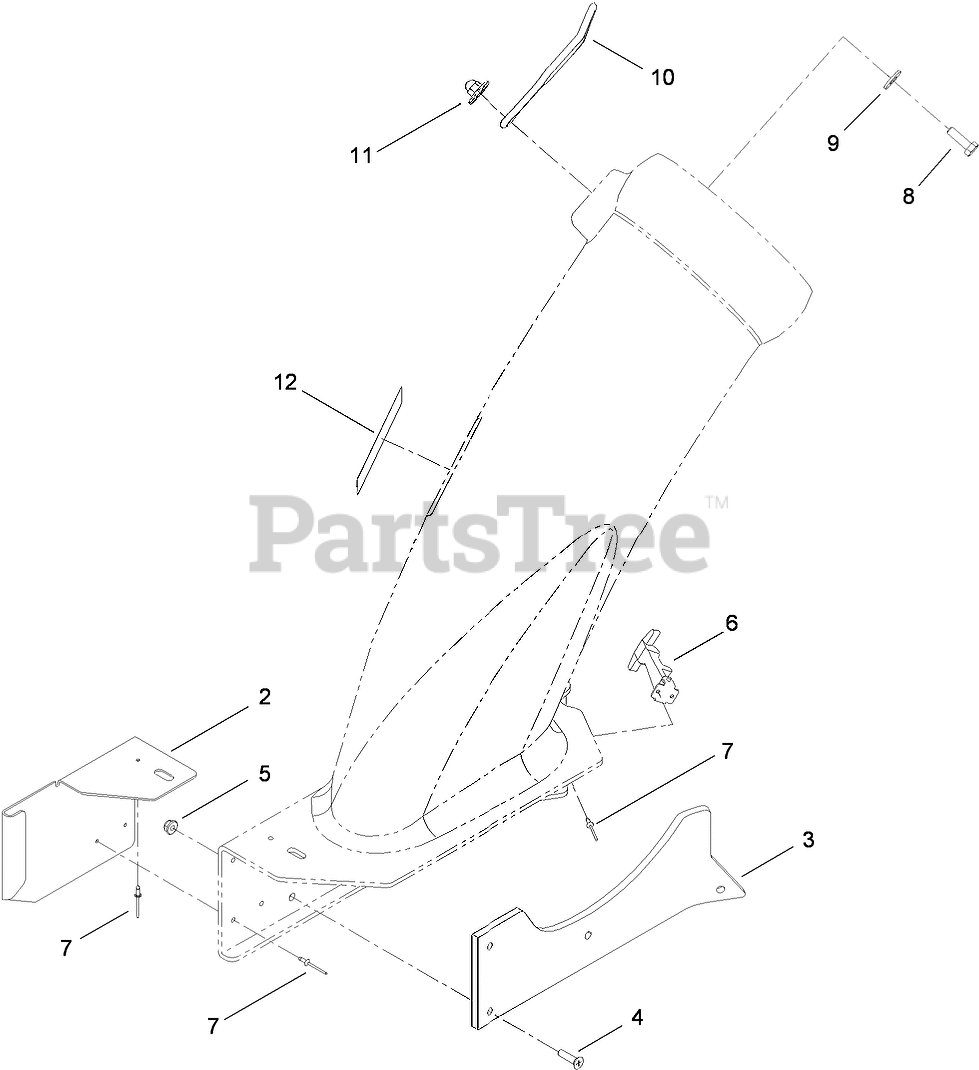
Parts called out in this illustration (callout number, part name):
2	PLATE-BAGGER
3	PLATE-SPACER
4	SCREW-FH
5	NUT-HF
6	HANDLE ASM
7	RIVET-POP
8	SCREW-HH
9	WASHER-FLAT
10	RETAINER-DUCT
11	NUT-IMPELLER
12	DECAL-DANGER
